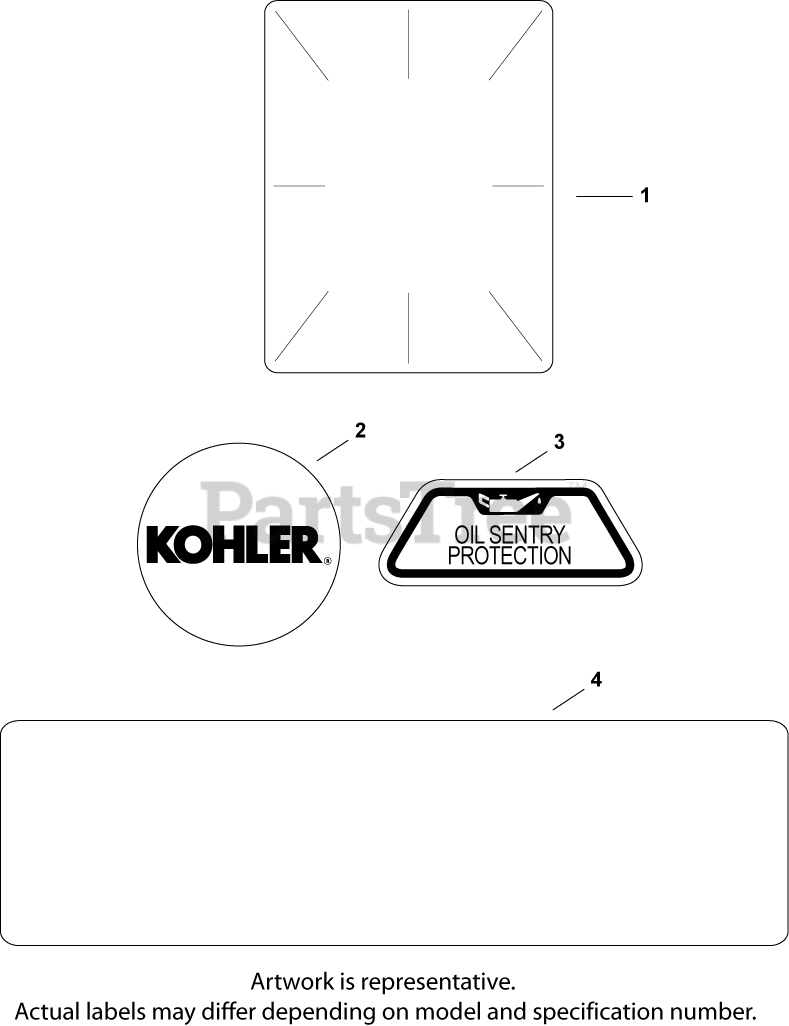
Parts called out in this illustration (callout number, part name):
1	DECAL, CLEAR LAMINATE USE 25 113 70-S
2	LABEL, (ROUND KOHLER GOLD)-USE 24 113 18
3	DECAL, OIL SENTRY - (#DSC)
4	DECAL, 22 HP
